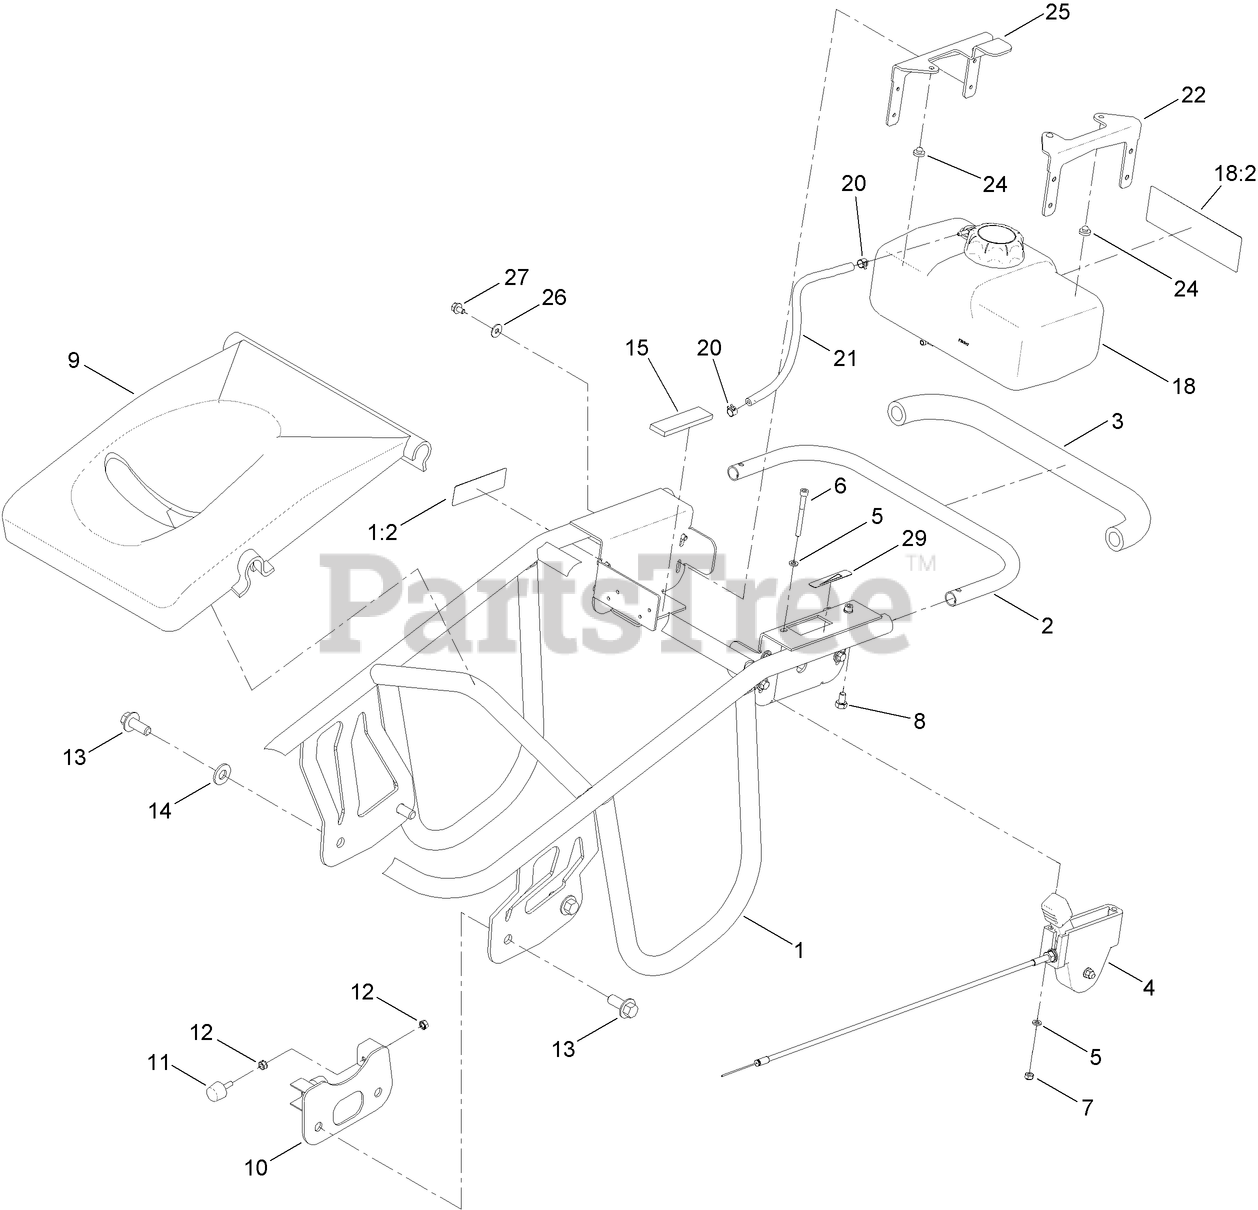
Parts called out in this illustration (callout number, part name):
1	HANDLE ASM
1:2	DECAL-ARRESTER, SPARK
2	HANDLE-GRIP, TUBE
3	GRIP-HAND
4	LEVER-THROTTLE
5	WASHER-FLAT
6	SCREW-HSH
7	NUT-LOCK
9	COVER-ENGINE
10	STOPPER
11	MOUNT-SHOCK
12	NUT-HEX
13	SCREW-HHF
14	WASHER
15	PAD-TANK, FUEL
18	1 GALLON FUEL TANK ASM
18:2	DECAL-WARNING
20	CLAMP-HOSE
21	HOSE-FUEL
22	BRACKET-TOP, FUEL TANK
24	BUMPER-RUBBER
25	GUARD-FUEL TANK, TOP
26	WASHER-FLAT
27	SCREW-HHF
29	DECAL-THROTTLE
